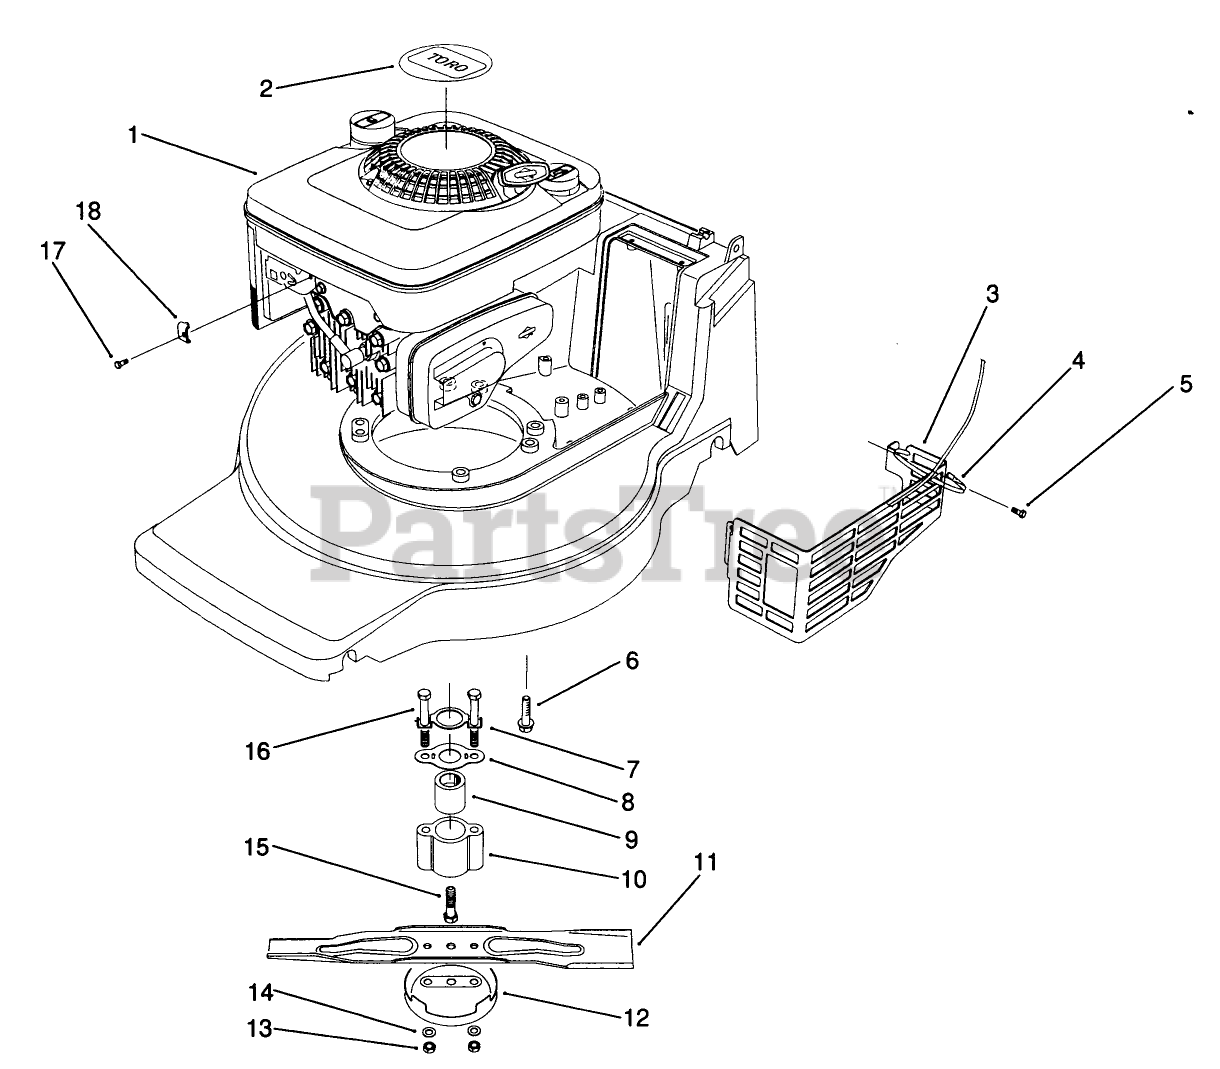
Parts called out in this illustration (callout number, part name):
1	Quantum
4	TIE-CABLE
6	3/8-16 X 2 CAPSCREW
7	BLADE RETAINER BRKT
8	SPRING FRICTION
14	WASHER
15	SCREW - CRANKSHAFT
16	SCREW - BLADE
18	CLAMP-CASING
